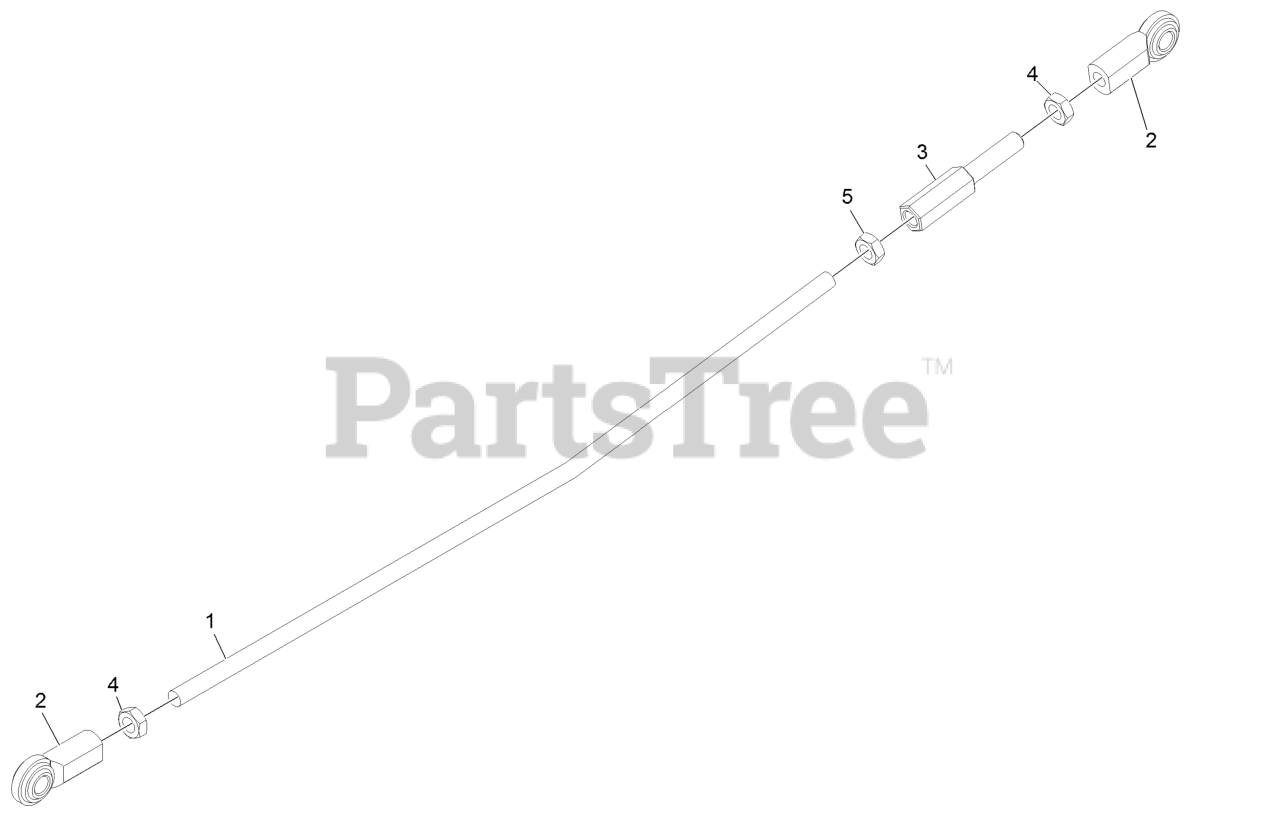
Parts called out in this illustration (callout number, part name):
1	LINK-LOWER, MOTION CONTRO
2	JOINT-BALL, END
3	ROD-ADJUSTMENT
4	NUT-HJ
5	NUT-HEX JAM, LH
